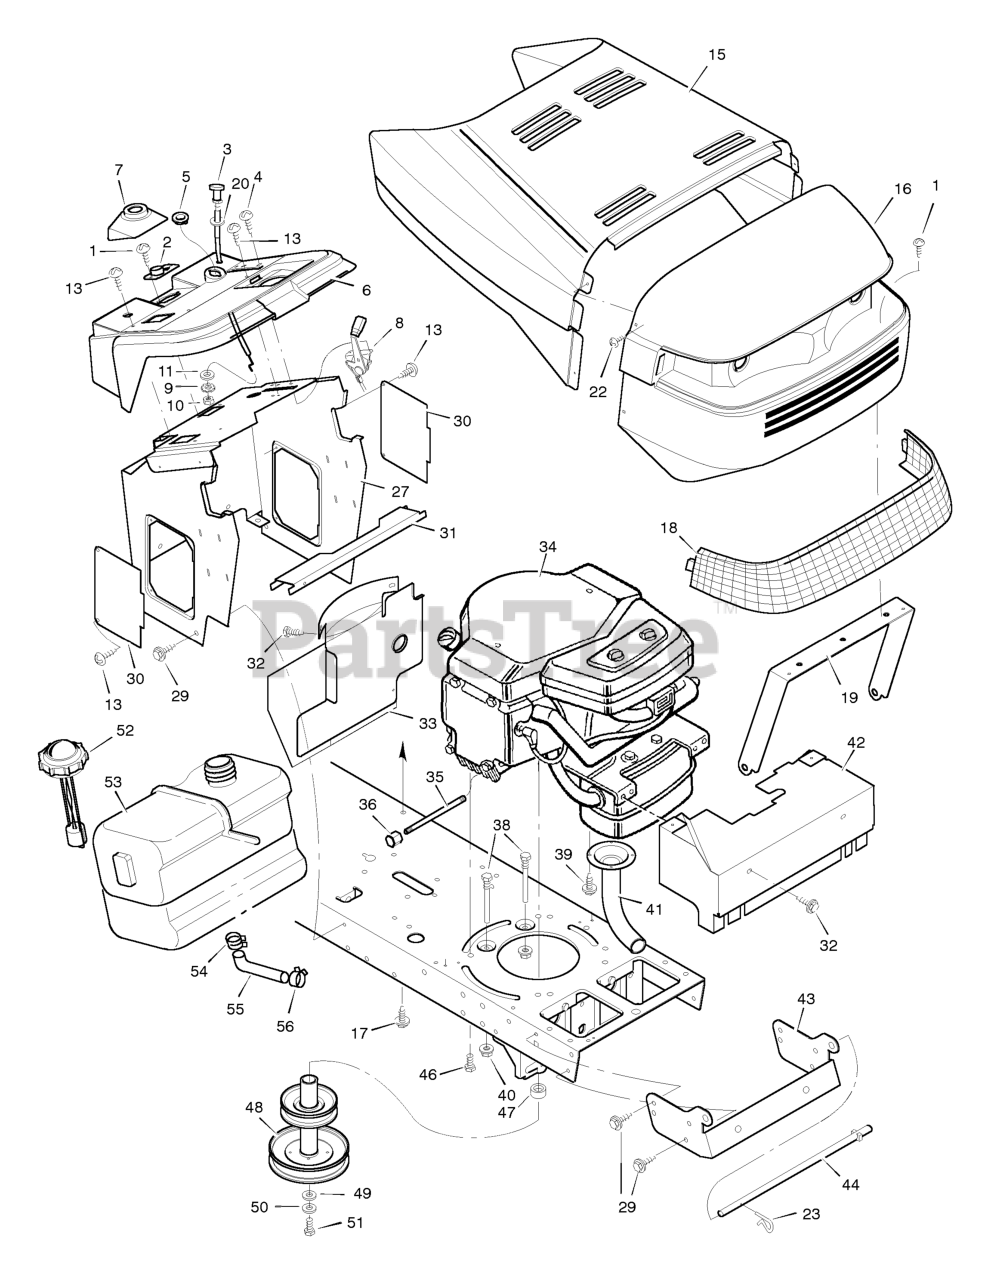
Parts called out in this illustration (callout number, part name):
2	Bearing, Steering Post
3	Cable, Choke
5	Bushing
7	Support, Bellows
8	Throttle Control
9	Lockwasher
10	Nut, Hex
13	Screw
15	Hood
16	Grille
19	Brace, Grille
20	Washer
23	Pin, Hair
27	Console Assembly
30	Panel, Side Access
31	Support, Fuel Tank
32	Screw
33	Baffle, Rear Heat
34	Engine *
35	Oil Drain Extension
36	Oil Drain Cap
38	Guide, Belt
40	Locknut, Flange
41	Pipe, Exhaust
42	Shield, Heat
43	Support, Grille
44	Rod, Pivot
46	Bolt, Hex
47	Spacer, Engine
48	Pulley Assembly, Stack
50	Lockwasher
51	Bolt, Hex
52	Cap, Fuel
53	Fuel Tank
54	Clamp, Hose
55	Fuel Line
56	Clamp, Hose
